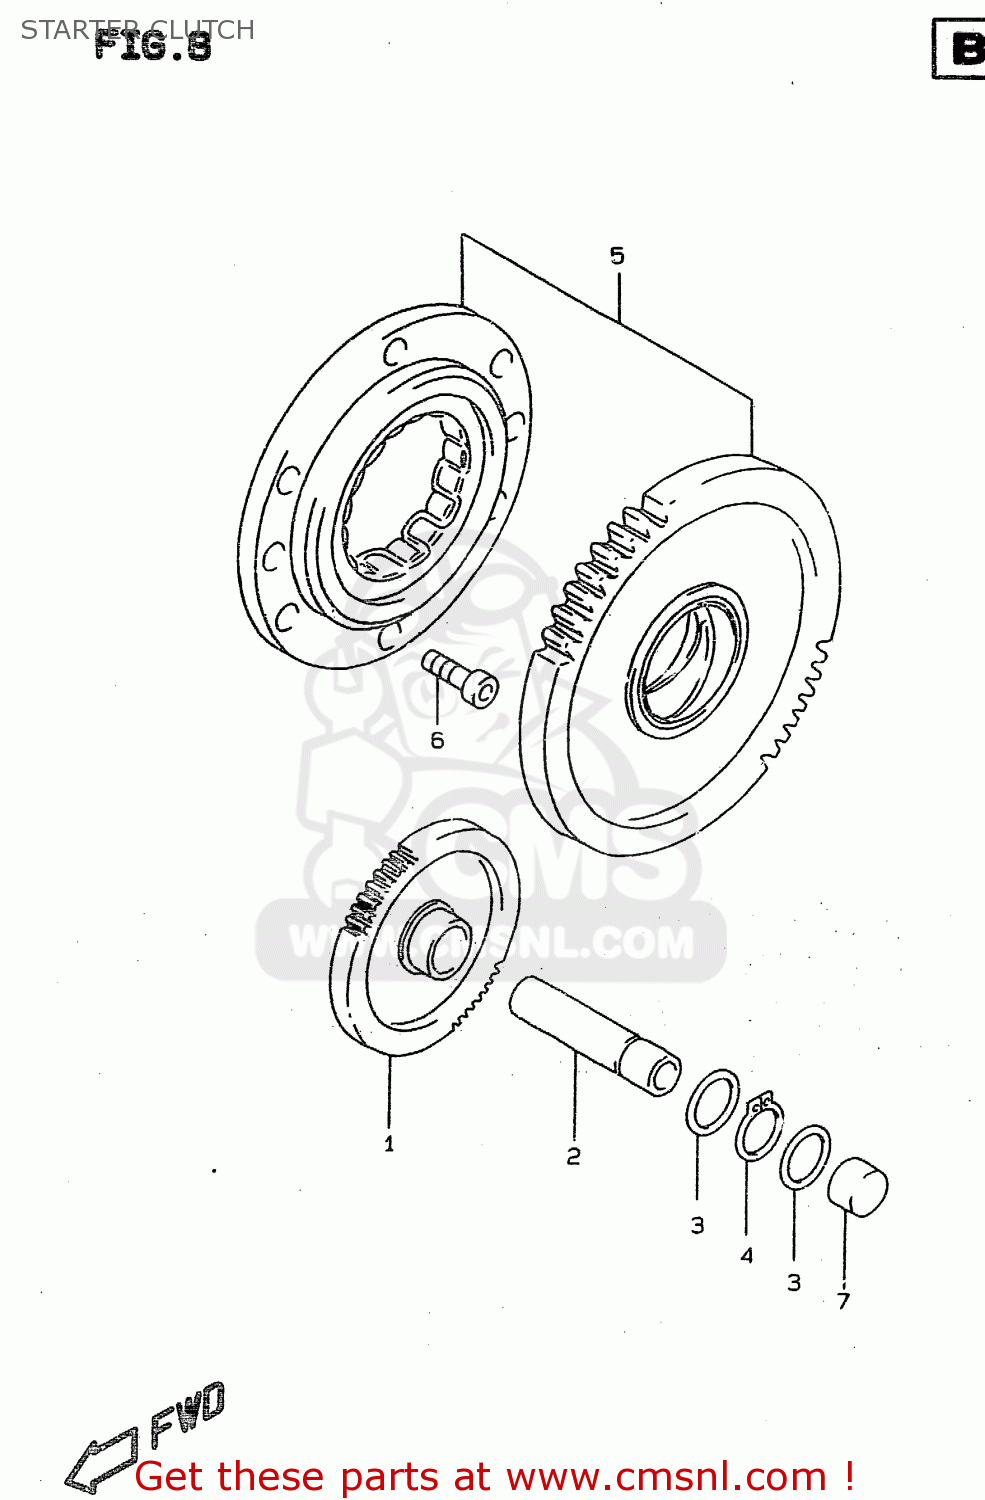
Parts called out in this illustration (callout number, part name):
1	GEAR,STARTER IDLE (NT:1
2	SHAFT,STARTER IDLE GEAR
3	WASHER
4	CIRCLIP,12 MM
5	CLUTCH SET,STARTER
6	BOLT,STRANGER
7	PLUG
